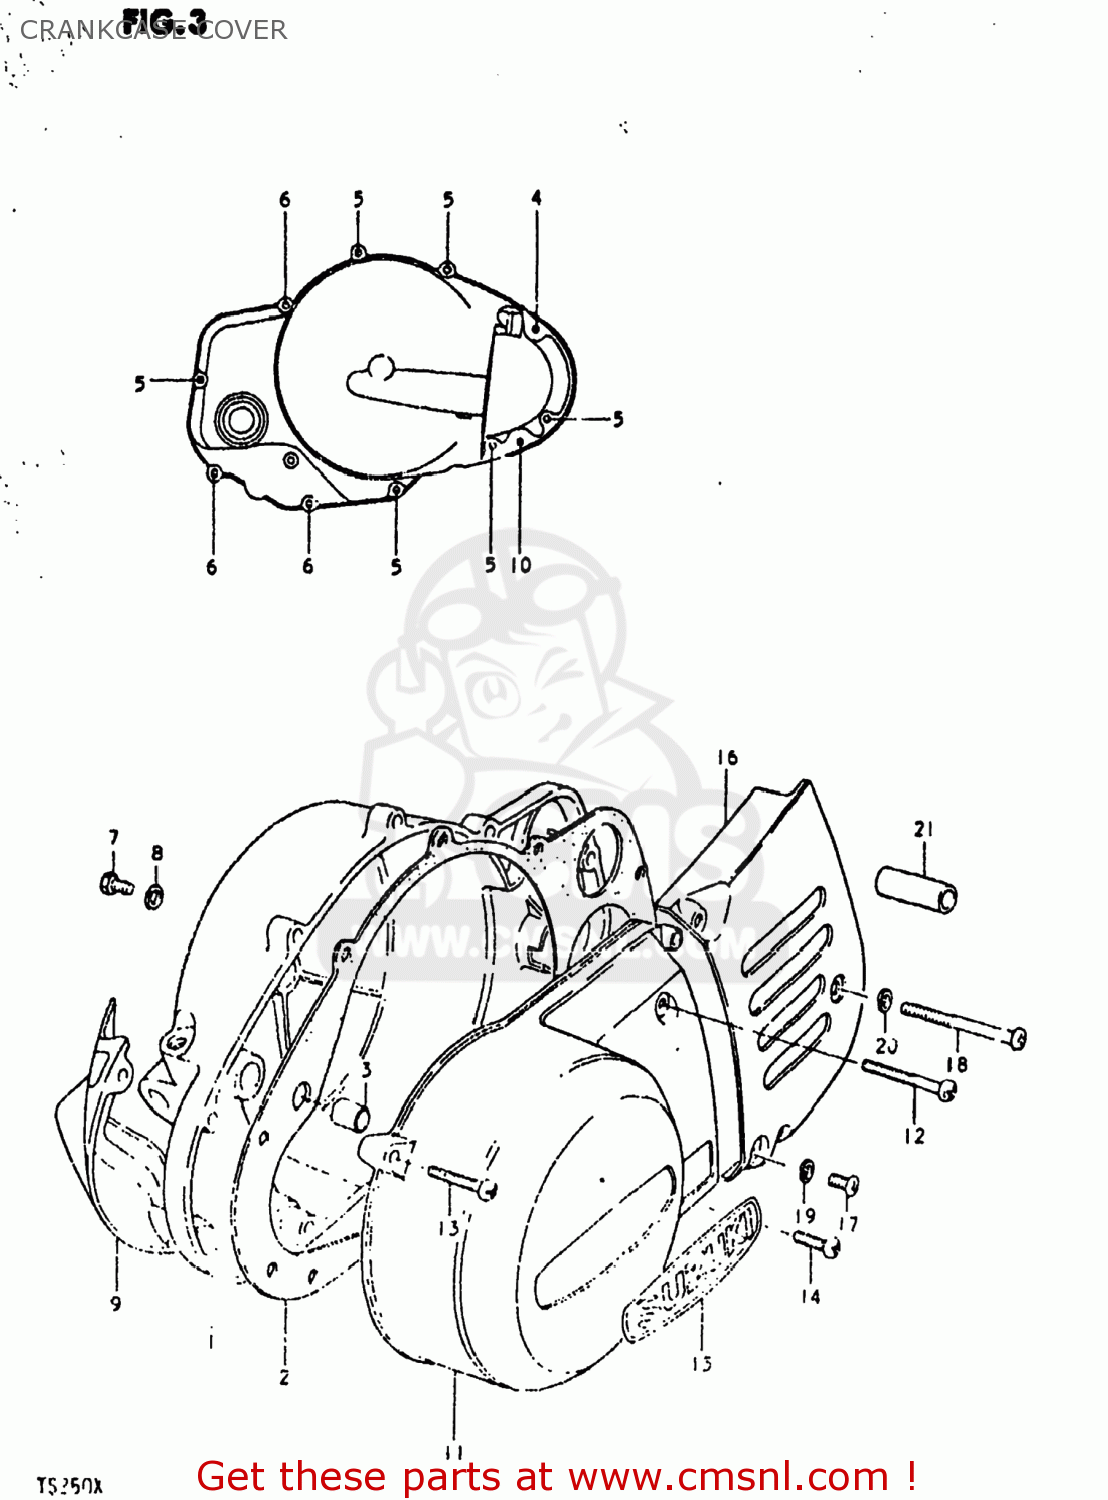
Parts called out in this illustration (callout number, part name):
1	COVER,CLUTCH
2	GASKET,CLUTCH COVER (MCA)
3	PIN
4	SCREW 6X30
5	SCREW
6	SCREW
7	SCREW(6X10)
8	GASKET(6.2X11X1) (NAS)
9	COVER,CLUTCH RELEASE A
10	SCREW
11	COVER,MAGNETO
12	SCREW (6X35)
13	SCREW
14	SCREW
15	EMBLEM,MAGNETO COVER
16	COVER,SPROCKET
17	SCREW
18	SCREW 6X60
19	LOCK WASHER
20	LOCK WASHER
21	CUSHION
